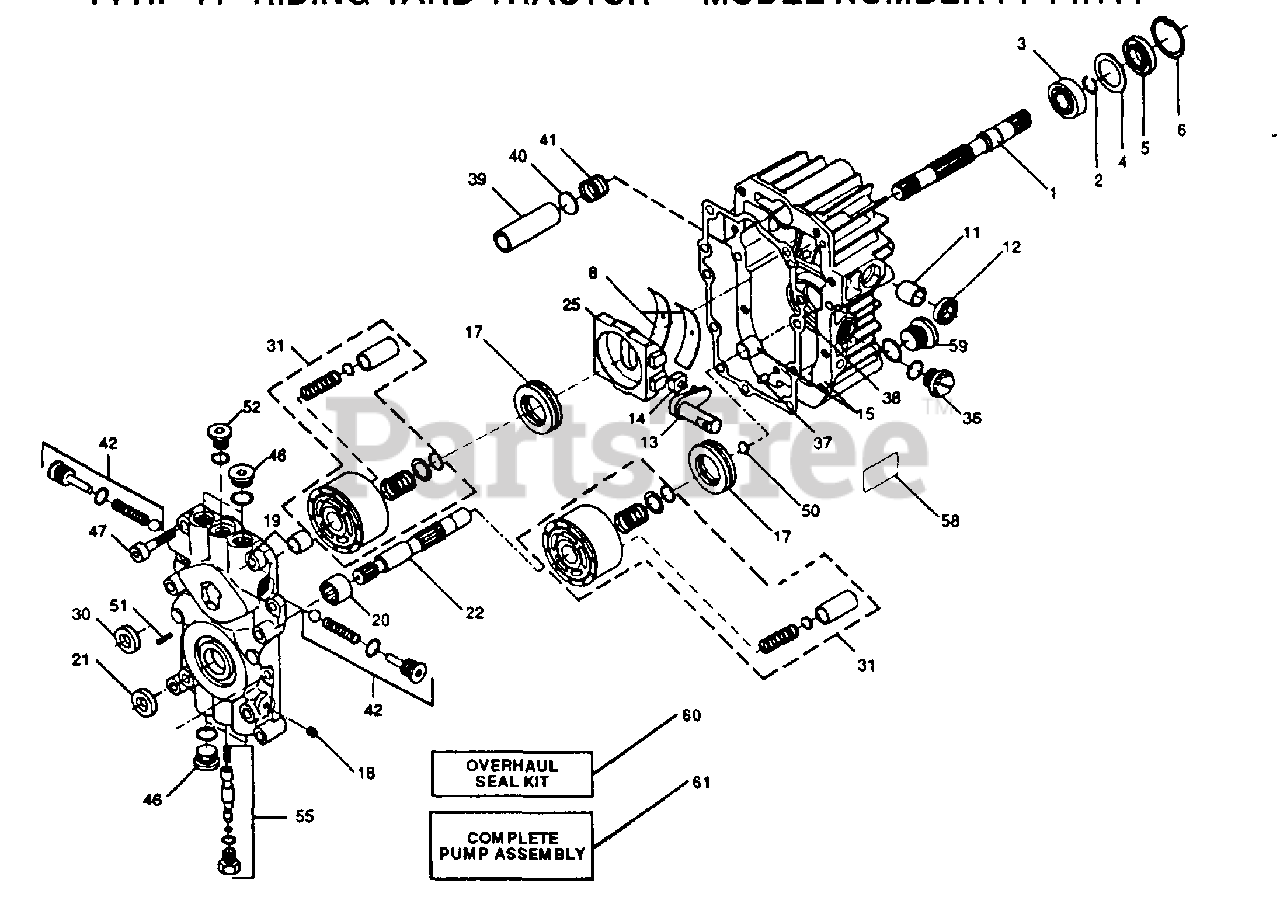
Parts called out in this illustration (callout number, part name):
1	Shaft, Pump Splined 36T
2	Ring, Retaining (AYP part number)
3	Bearing, Ball
5	Seal, Lip, Pump Shaft (AYP part number)
6	Ring, Retaining (AYP part number)
8	Bearing, Cradle (AYP part number)
11	Bearing, Journal Trunnion
12	Seal, Lip (AYP part number)
13	Arm, Trunnion
14	Guide, Slot
15	Housing (AYP part number)
16	Bearing, Journal
17	Bearing, Asm. Ball (AYP part number)
18	Plug, Pipe
19	Section, Center
20	Bearing, Needle
21	Seal, Lip, Motor Shaft
22	Shaft, Motor Splined 36 Tooth
23	Washer
25	Swashplate (AYP part number)
26	Guide, Bearing (AYP part number)
27	Washer, Thrust (AYP part number)
28	Roller, Thrust
29	Plate, Thrust (AYP part number)
30	Seal, Lip, Thru Pump Shaft
31	Cylinder, Block (AYP part number)
32	Cylinder Block
34	Piston, Spring
35	Washer, Thrust
37	Pin, St. Hdls.
38	Gasket
40	Washer, Filter
41	Spring, Filter
42	Plug, Check Valve
45	Check, Spring
46	Plug, Std. Thd. (AYP part number)
47	Screw, Socket Hd. M8 X 35
48	Screw, Socket Hd. M8 X 20
50	Washer, Thrust
51	Pin, Spiral
52	Plug, St, Thd.
53	O-Ring Bypass Valve
55	Bypass Spool
56	Bypass Plug
57	O-Rings, Bypass Valve
58	Nameplate (outside vendor part)
59	Plug, Plastic
61	Pump Assy. Complete
